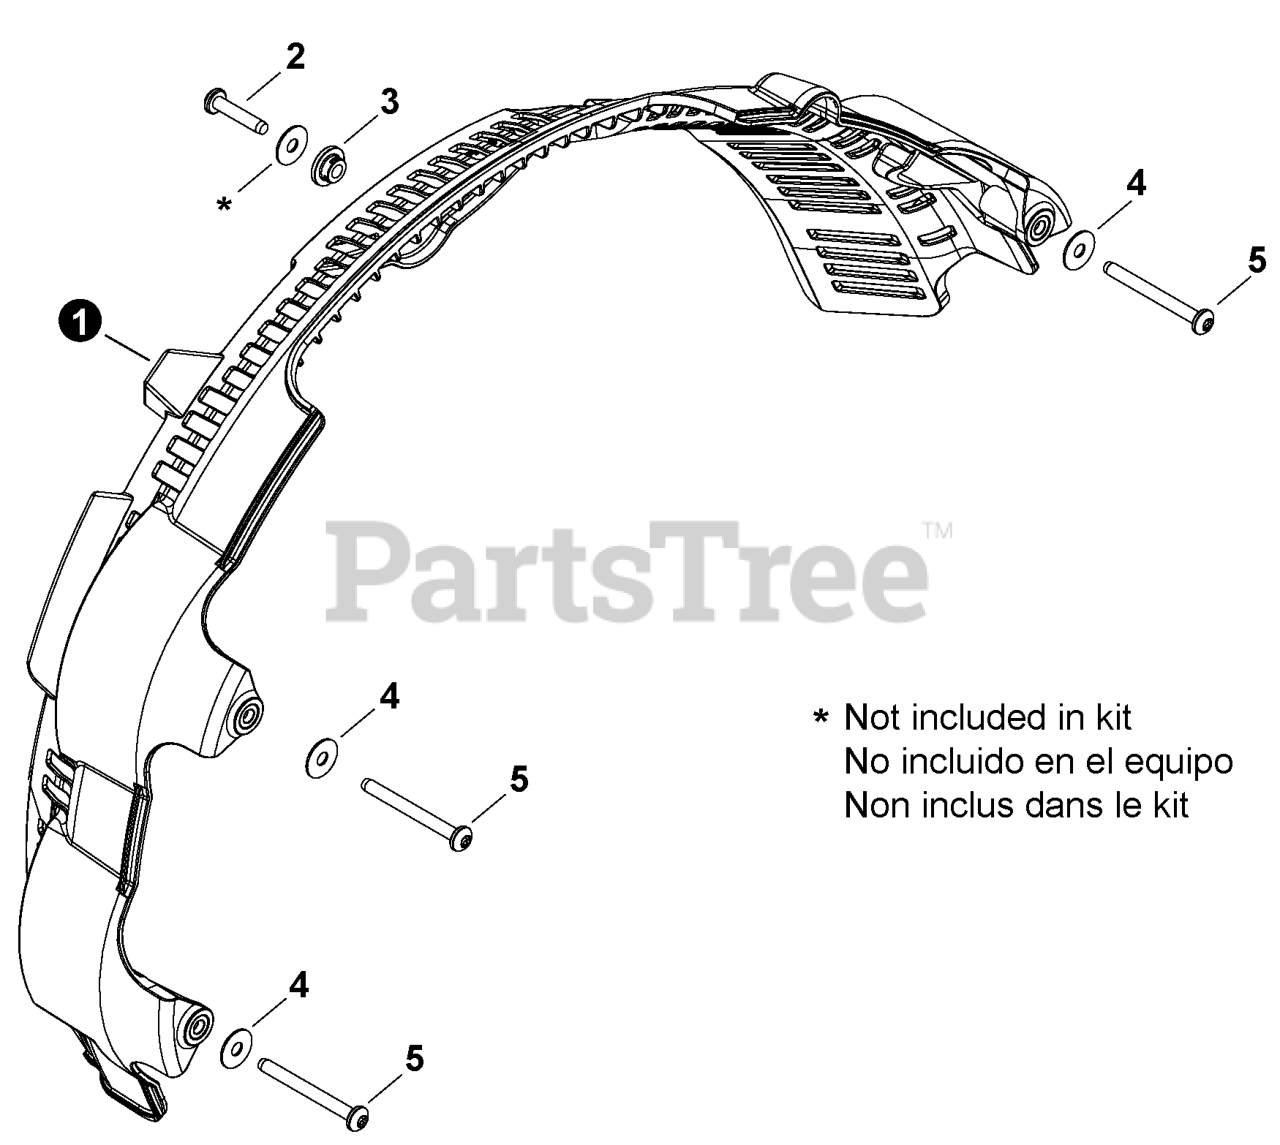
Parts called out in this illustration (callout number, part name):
1	GUARD, LEAF
2	BOLT, TORX 5x25
3	COLLAR 5
4	WASHER 5.5x16x0.8
5	BOLT, TORX 5x50
